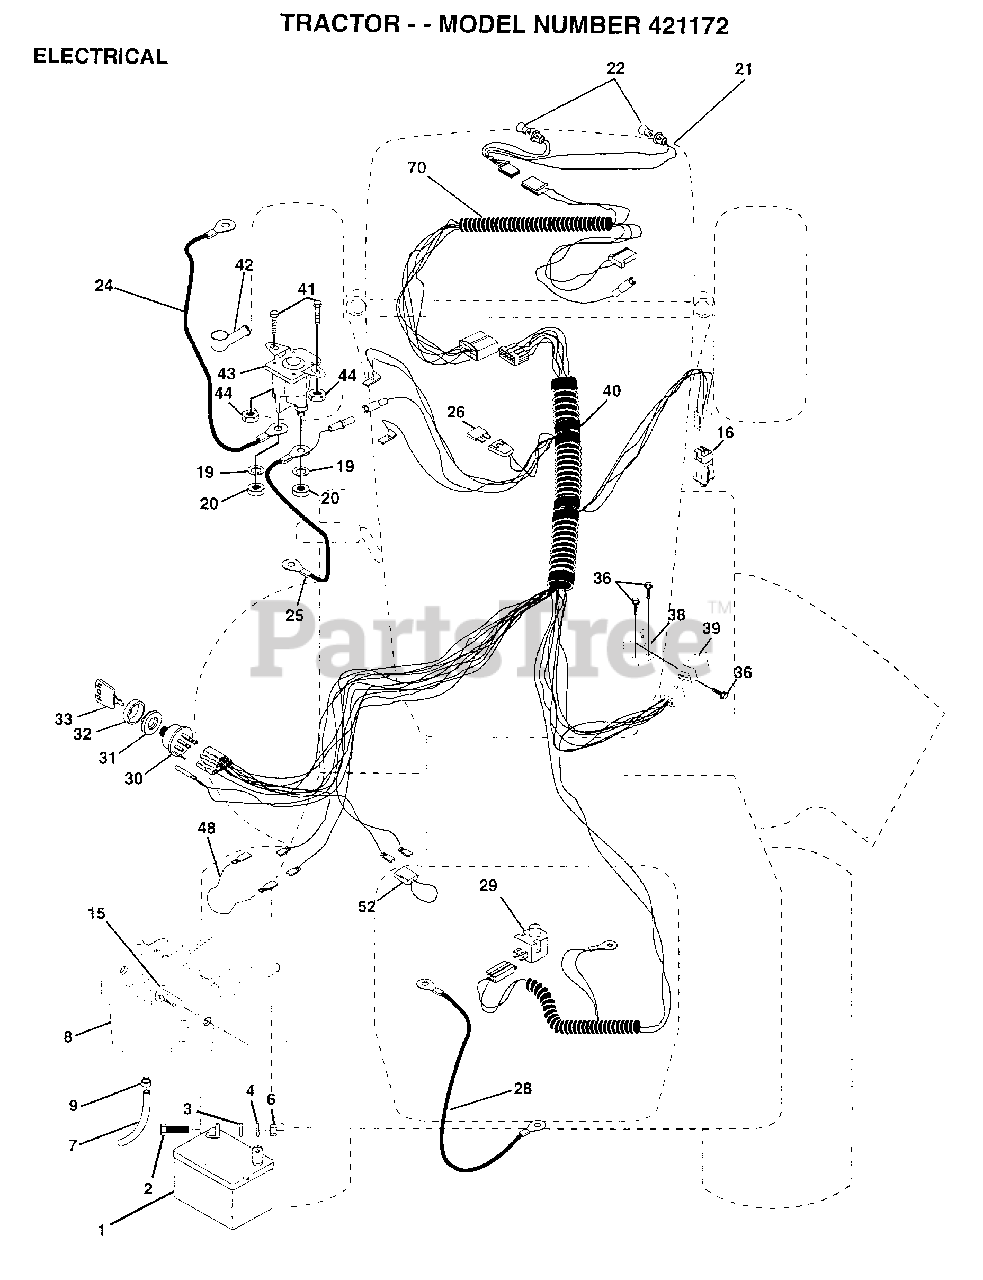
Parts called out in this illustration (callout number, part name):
2	BOLT LT
3	WASHER
4	LOCKWASHER
7	TUBE T
9	HOSE CLAMP T
15	FASTNER.SNAP-IN
16	SWITCH INTERLOCK
20	NUT
21	"HARNESS,LIGHT SOC"
22	HEADLAMP BULB
24	CABLE-BATTERY T
25	CABLE.BTRY.6GA.RD
26	FUSE HYT
28	CABLE T
29	SWITCH SEAT
30	SWITCH IGN 4POS
31	NUT IGNITION
32	COVER KEY SWITCH
33	KEY
36	SCREW
38	BRACKET SWITCH IN
39	SWITCH INTERLOCKT
40	HARNESS.IGNITION
41	BOLT HXHD FIN
44	NUT HXKEP 1/4X20
48	ADAPTER AMMETER
52	PROTECTION LOOP
70	HARNESS.ENG.LT.
